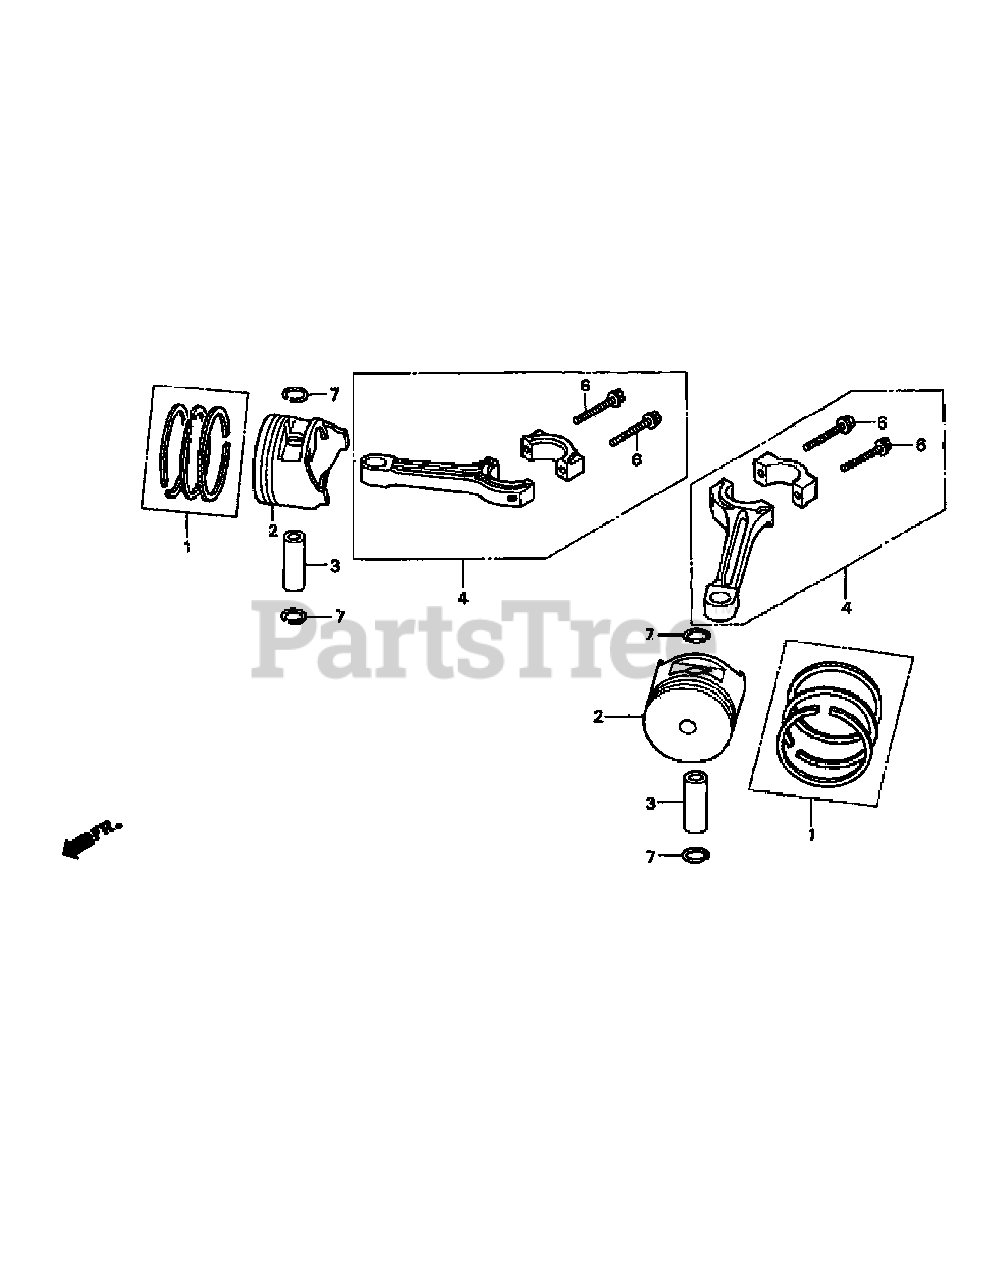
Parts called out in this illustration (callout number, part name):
1	Piston Ring Set (Std.)
1	Piston Ring Set (OS .25)
1	Piston Ring Set (OS .50)
1	Piston Ring Set (OS .75)
2	Piston (Std.)
2	Piston (OS .25)
2	Piston (OS .50)
2	Piston (OS .75)
3	Piston Pin
4	Connecting Rod Assy.
6	Connecting Rod Bolt (6x37)
7	Piston Pin Clip
